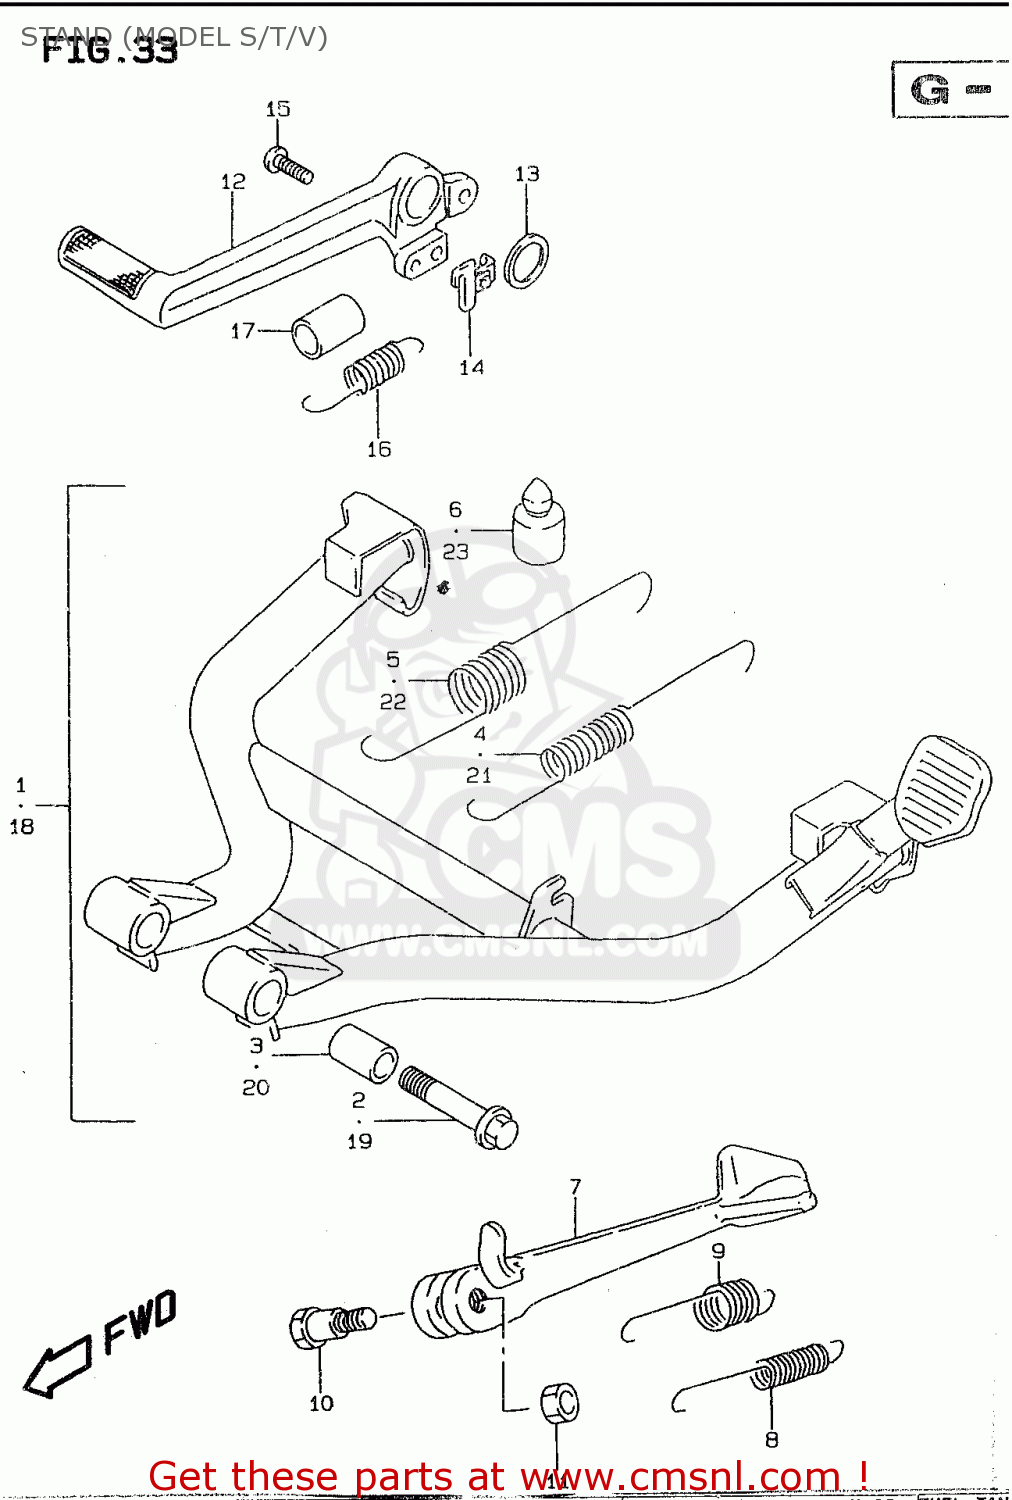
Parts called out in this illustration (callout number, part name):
1	STAND,CENTER
2	BOLT(10X48)
3	SPACER(10X16X25.5)
4	SPRING
5	SPRING OUTER
6	CUSHION
7	STAND,PROP
8	SPRING
9	SPRING
10	BOLT(10X34)
11	NUT
12	PEDAL,BRAKE
13	WASHER(18X24X1)
14	BRACKET,STOP LAMP SWITCH SPR
15	SCREW
16	SPRING
17	TUBE,BRAKE SPRING GUIDE
18	STAND,CENTER
19	BOLT(10X48)
20	SPACER(10X16X25.5)
21	SPRING
22	SPRING OUTER
23	CUSHION
